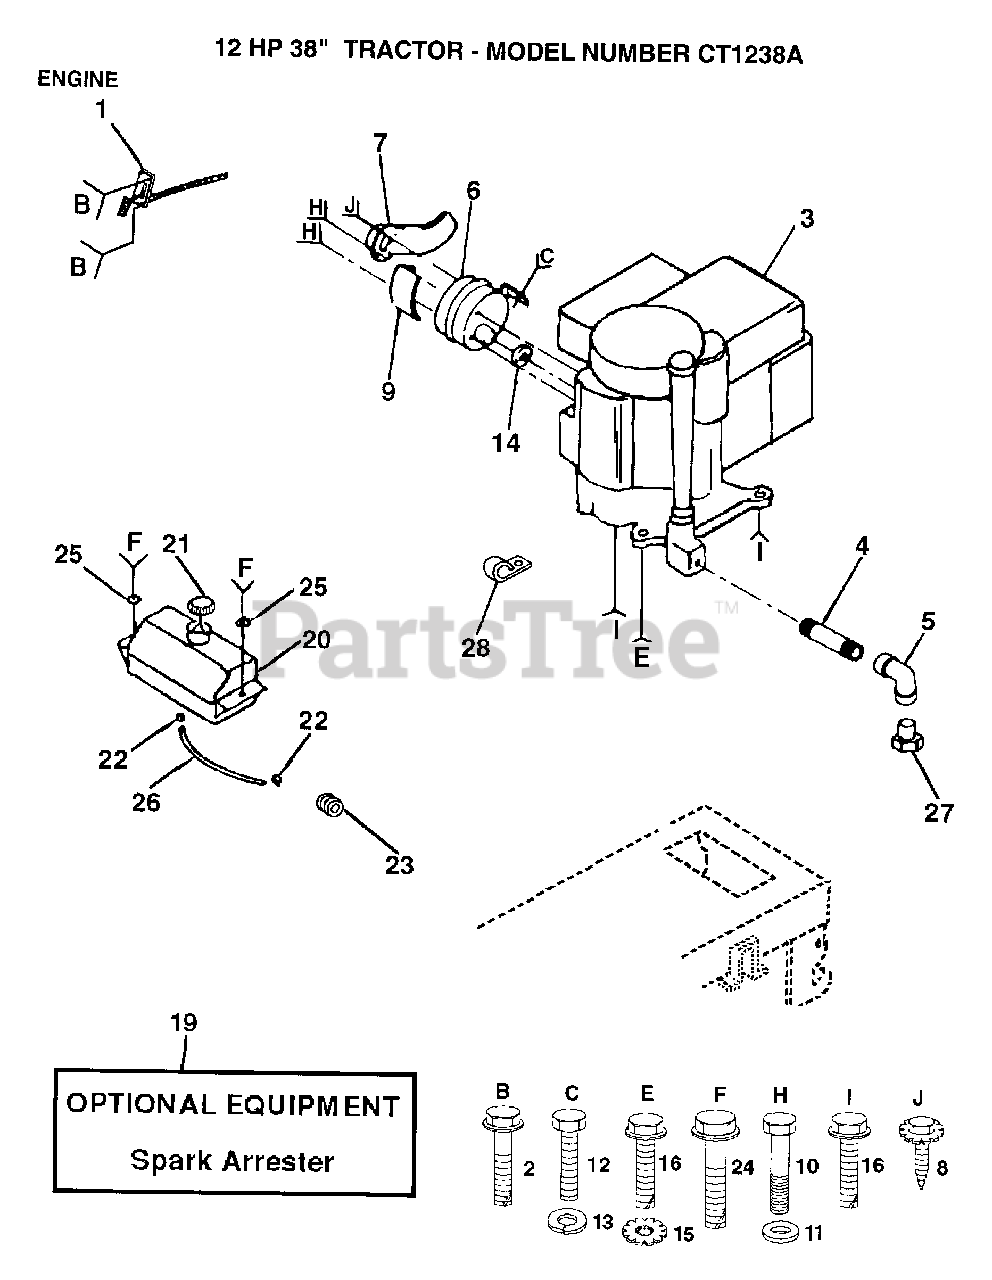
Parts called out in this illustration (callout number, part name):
1	THROTTLE CONTROL
2	SCREW LT
3	ENG B&S 10-12.5HP PWRBLT DC
4	PIPE NIPPLE
5	ELBOW
6	MUFFLER LTV
7	DEFLECTOR MUFFLER
9	SHIELD HEAT LTV
10	"BOLT,HEX"
11	WASHER T
12	BOLT
13	LOCKWASHER
15	LOCKWASHER
16	SCREW
20	TANK.FUEL.LT.
22	HOSE CLAMP
24	SCREW
25	WASHER GT
26	FUEL LINE T
28	CLIP T
